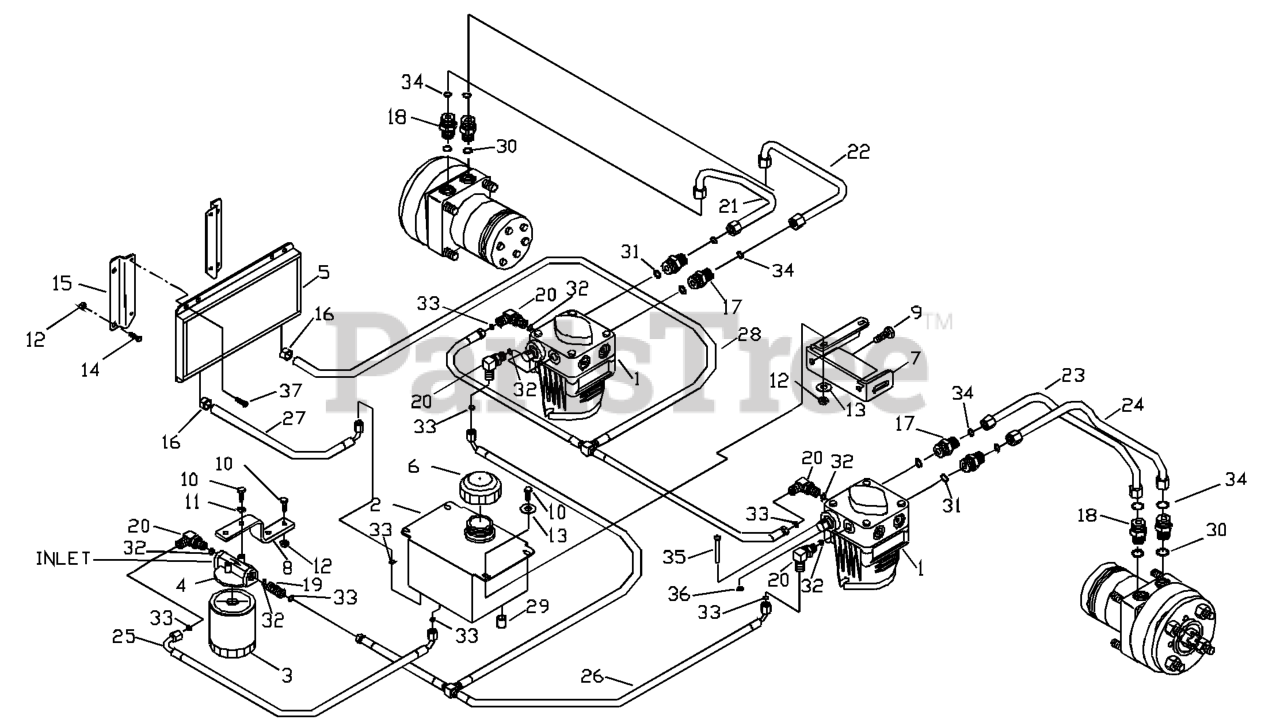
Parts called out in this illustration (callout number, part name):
1	PUMP
3	HYDRAULIC OIL FILTER
4	FILTER HEAD
6	HYDRAULIC CAP
7	TANK MOUNT LT
7	TANK MOUNT RT
8	FILTER MOUNT
9	HCS 5/16C X 3/4
10	HCS 1/4C X 3/4 HCS
11	LOCKWASHER 1/4"
12	NUT 1/4C CENTERLOCK
13	WASHER 1/4 FLAT
14	HCS 1/4C X 2
15	FRONT COOLER BRKT
15	COOLER BRACKET
16	HOSE CLAMP T-1865
17	FITTING, STRAIGHT F6400-8-8-0
19	STRAIGHT FITG
20	ELBOW, F6801-6-6-0 90 DEGREE
21	RUBBER HYDRAULIC HOSE (1)
22	RUBBER HYDRAULIC HOSE (1)
23	RUBBER HYDRAULIC HOSE (1)
24	RUBBER HYDRAULIC HOSE (1)
29	NUT 9/16-18 JIC CAP
35	CLEVIS PIN
36	NUT PUSH
37	HEX CAP SCREW 1/4
